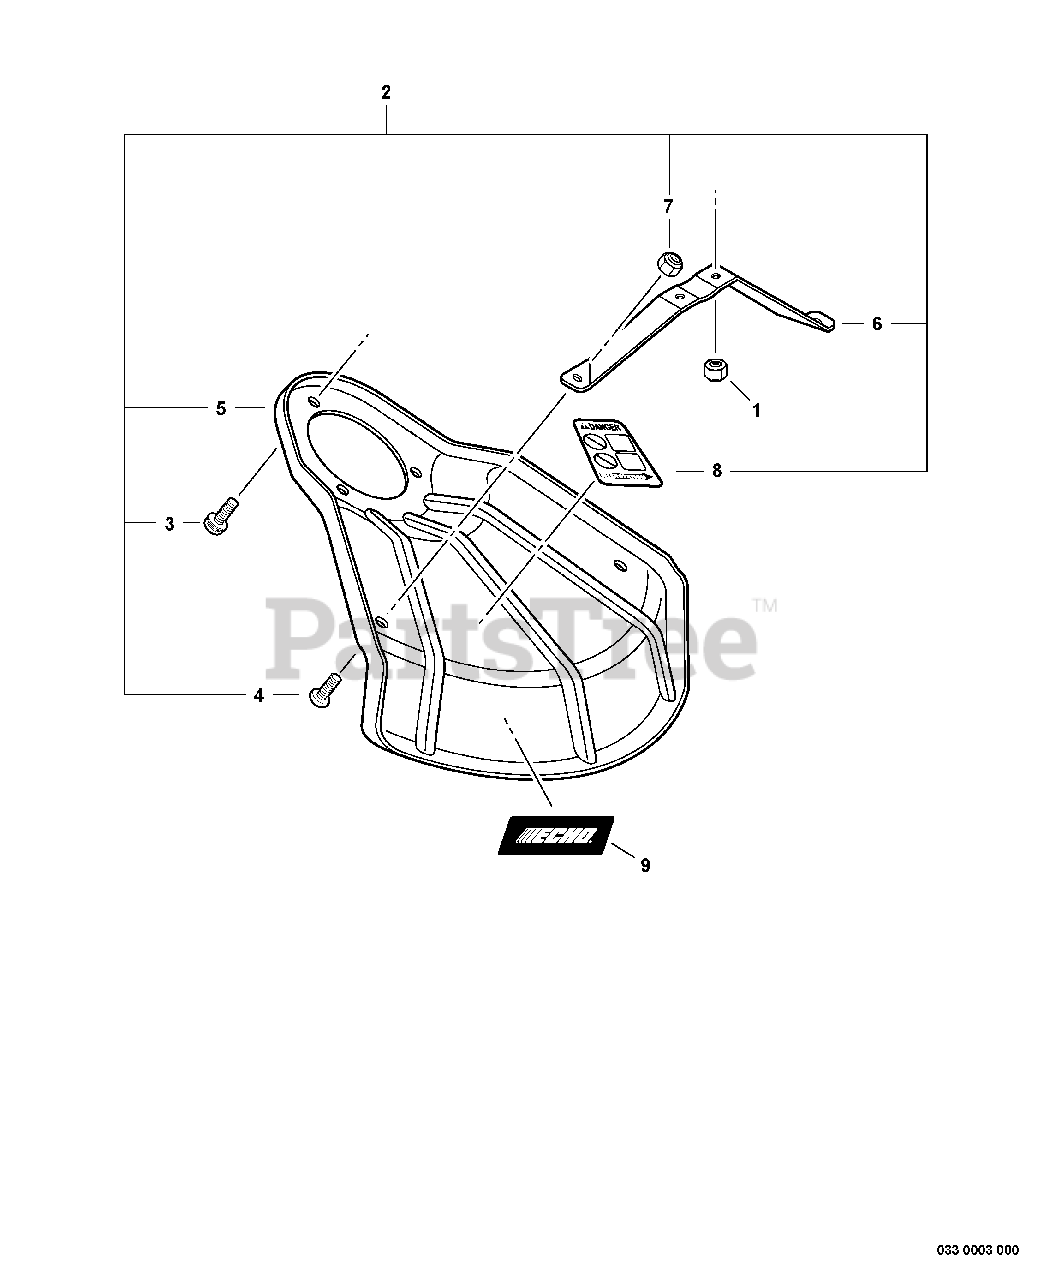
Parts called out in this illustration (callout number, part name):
1	LOCKNUT - 5
2	DEBRIS SHIELD KIT
3	SCREW - 5X10
4	SCREW - 5X8
5	SHIELD, DEBRIS - METAL
6	BRACKET, SHIELD
7	LOCKNUT - 5
8	LABEL - DANGER
9	LABEL - ECHO
